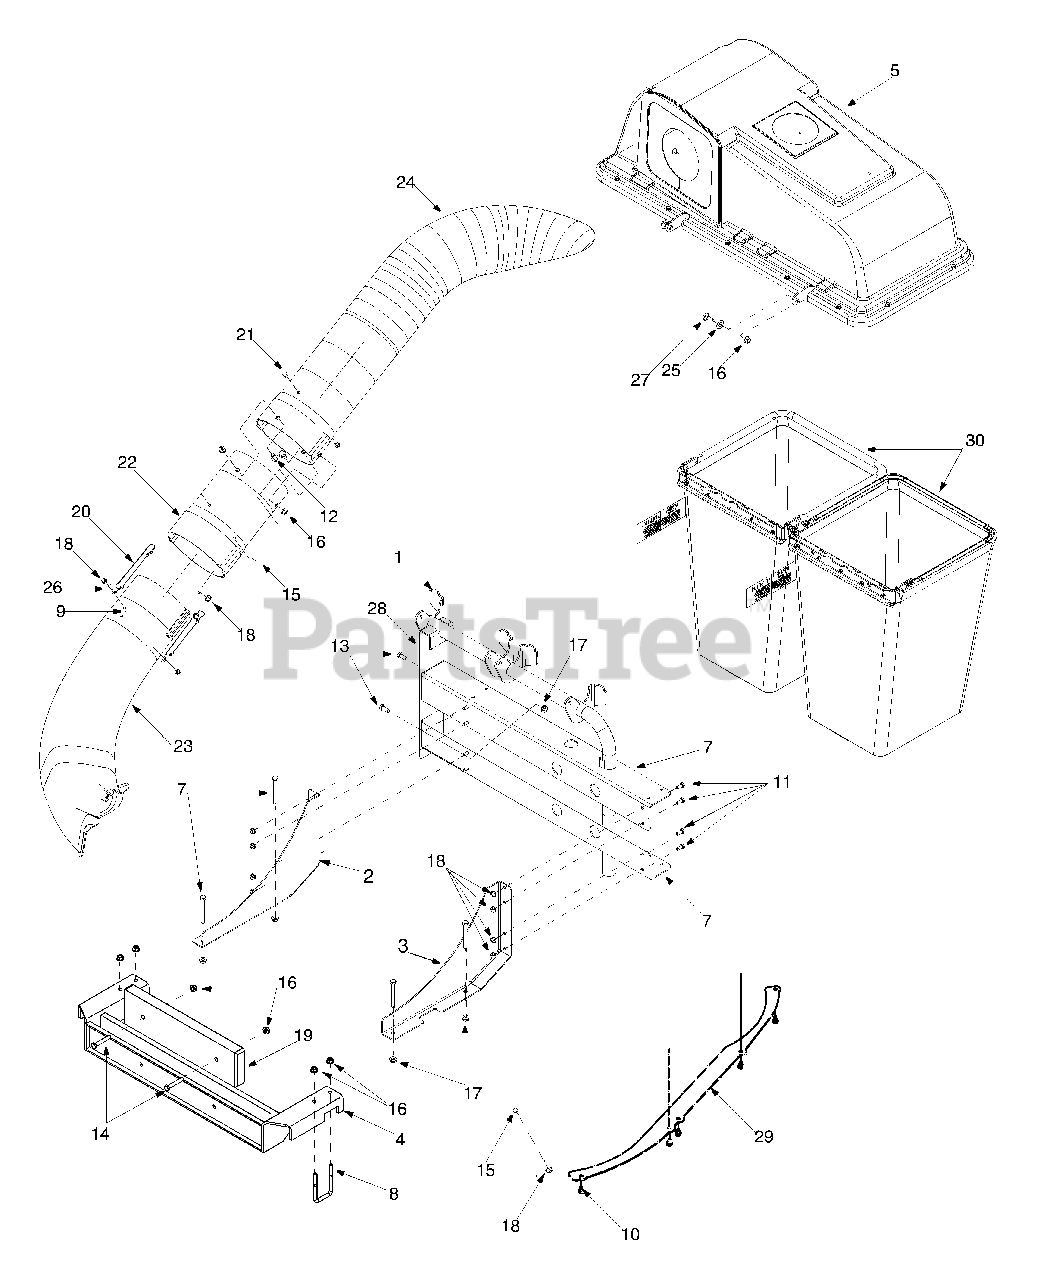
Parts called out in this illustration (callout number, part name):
7	Hex Bolt 5/16-18 x 2.75
9	Hex Bolt 1/4-20 x 1.0
10	TT Screw 1/4-20 x 0.5
11	Hex Bolt 1/4-20 x 0.620
12	Hex Bolt 3/8-16 x 0.625
13	Hex Bolt 5/16-18 x 0.75
14	Hex Bolt 3/8-16 x 2.25
15	Grasscatcher Pin
16	Flange Lock Nut 3/8-16
17	Flange Lock Nut 5/16-18
18	Flange Lock Nut 1/4-20
19	Weight Bar
20	Retainer Strap: Chute
22	Chute Extension
23	Discharge Chute
24	Chute Extension
25	Bell Washer
26	Flat Washer
27	Shoulder Screw
30	Grass Bag Assembly
